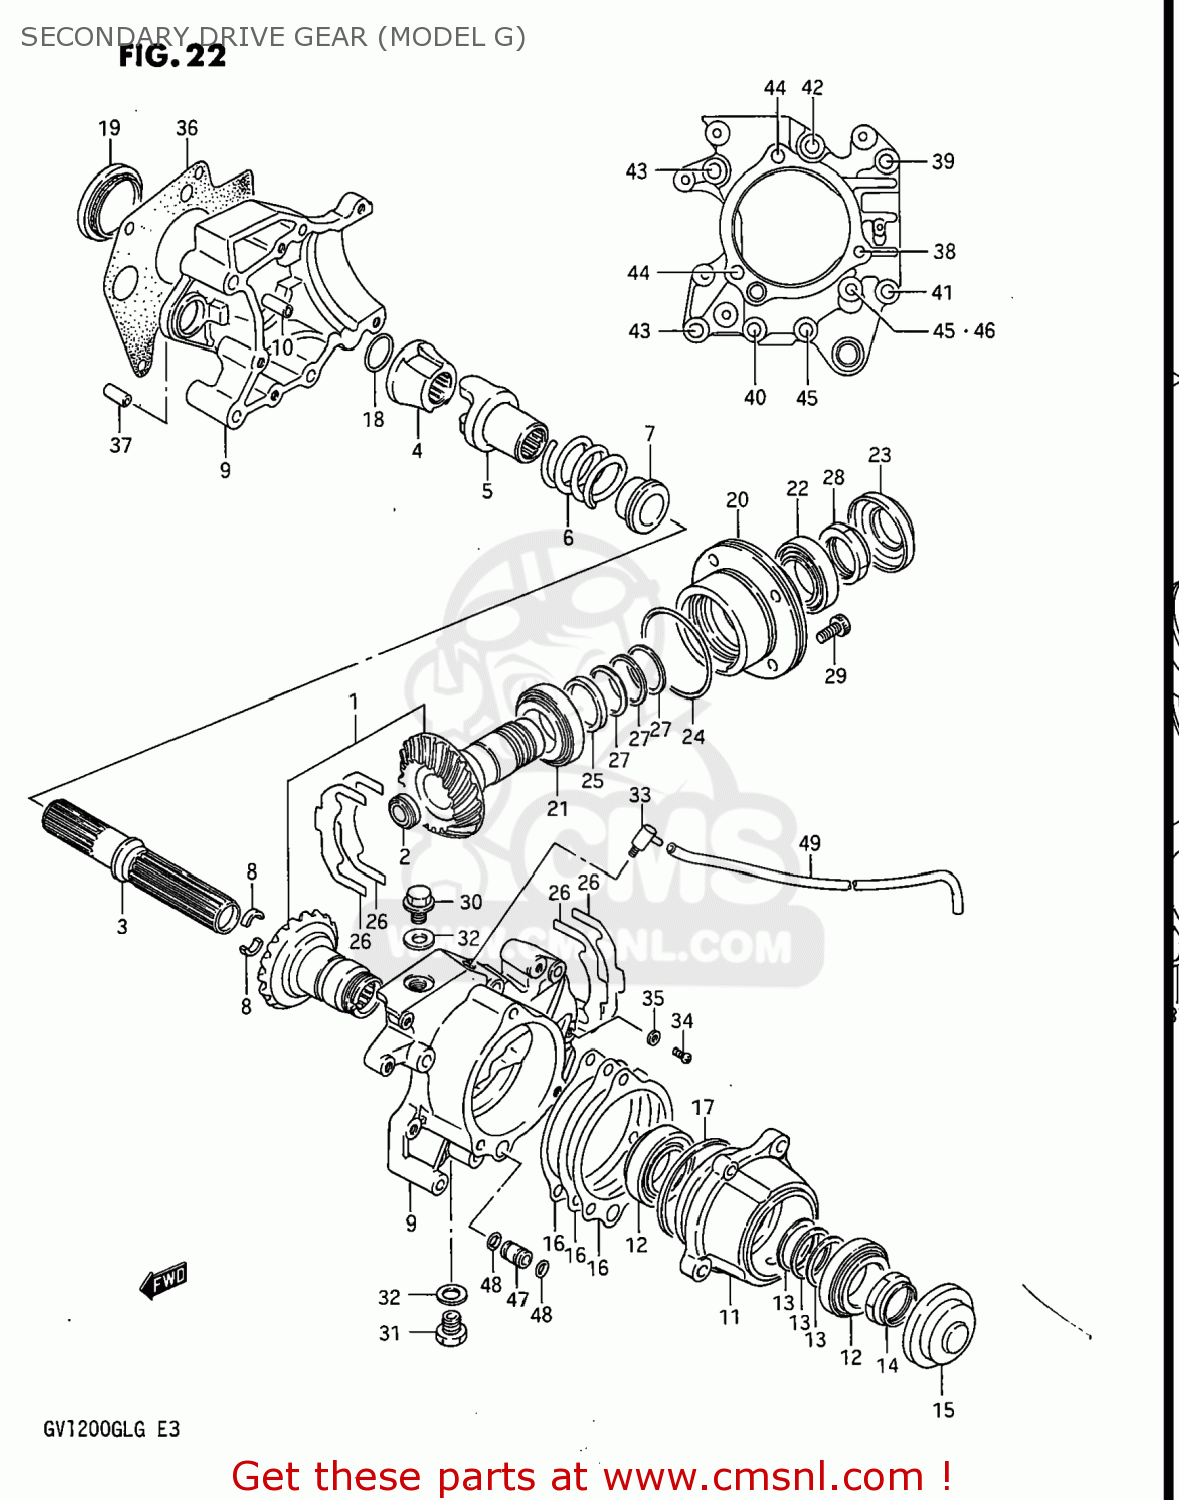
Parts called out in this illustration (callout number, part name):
2	PLUG
3	SHAFT,SECONDARY DRIVEN,FRONT
4	DOG,CAM
6	SPRING
8	STOPPER,CAM DOG
10	PIN (11X20)(SUS)
11	HOUSING,SECONDARY DRIVE SHIM
12	BEARING(35X62X18)
13	SHIM
14	NUT,SECONDARY DRIVE BELT
15	PLUG
16	SHIM,SECONDARY DRIVE
17	O-RING
18	O RING(D:1.9,ID:29.7)
19	OIL SEAL
20	HOUSING,SECONDARY DRIVEN BEVEL
21	BEARING(35X62X18)
22	BEARING(32X58X17)
23	OIL SEAL
24	O RING(D:2.1,ID:66.2)
25	SPACER(32.4X40X3)
26	SHIM,SECONDARY DRIVEN HOUSING
27	SHIM(32X38X2)
28	NUT
29	BOLT
30	PLUG (14X12)
31	PLUG
32	GASKET(14X19.2X2) (NAS)
33	BPLUG,BEVEL GEAR BREATHER
34	SCREW
35	GASKET(5.3X9.3X1.2) (NAS)
36	GASKET,SECONDARY GEAR
37	PIN(10.4X13X22)
38	BOLT
39	BOLT
40	BOLT 8X60
41	BOLT (8X65)
42	BOLT 8X85
43	BOLT (8X90)
44	BOLT (8X95)
45	BOLT
46	GASKET(8.2X14X1) (NAS)
47	PIN,OIL GALLERY
48	O-RING
49	HOSE
